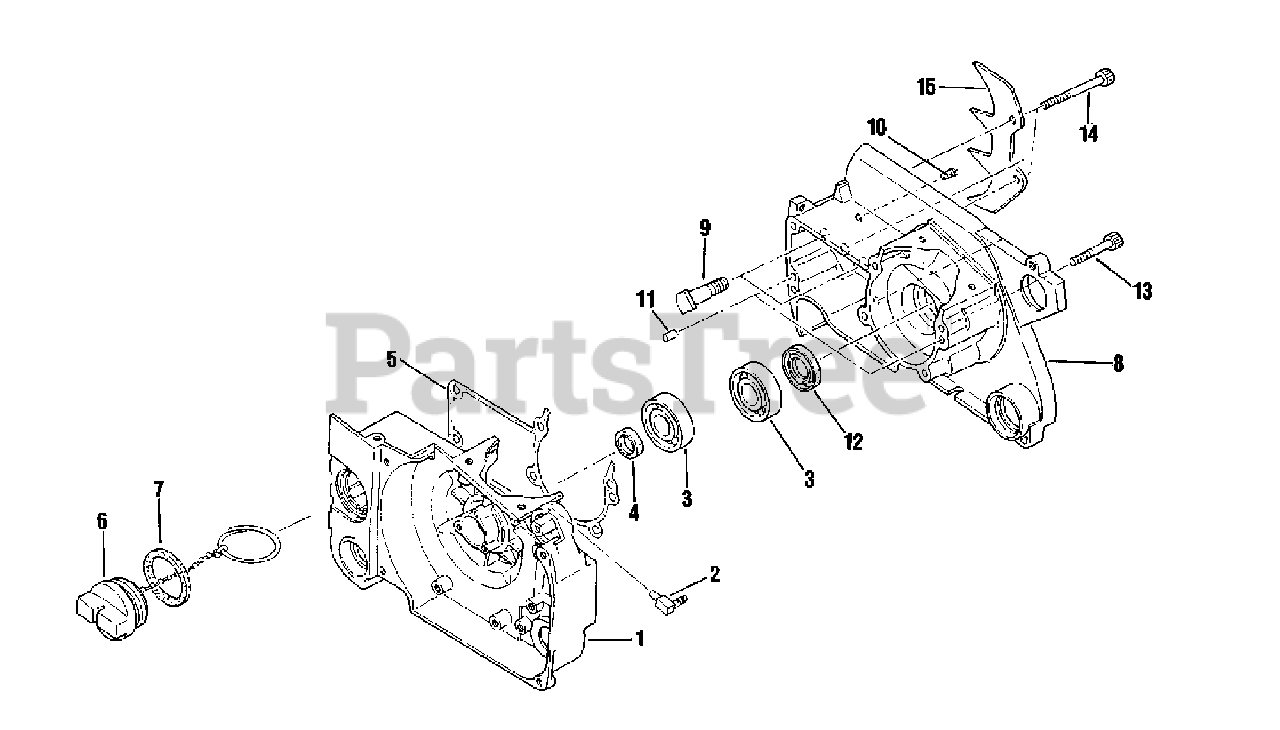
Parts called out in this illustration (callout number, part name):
1	CRANKCASE ASSY
2	CONNECTOR, PIPE
3	BEARING, BALL - 6202
4	SEAL, OIL
5	GASKET, CRANKCASE
6	CAP, OIL
7	GASKET
8	CRANKCASE ASSY - C
9	STUD, GUIDE BAR
10	VALVE, CHECK
11	PIN - LOCATING
12	SEAL, OIL
13	SCREW - 5X35
14	SCREW - 5X50
15	SPIKE
